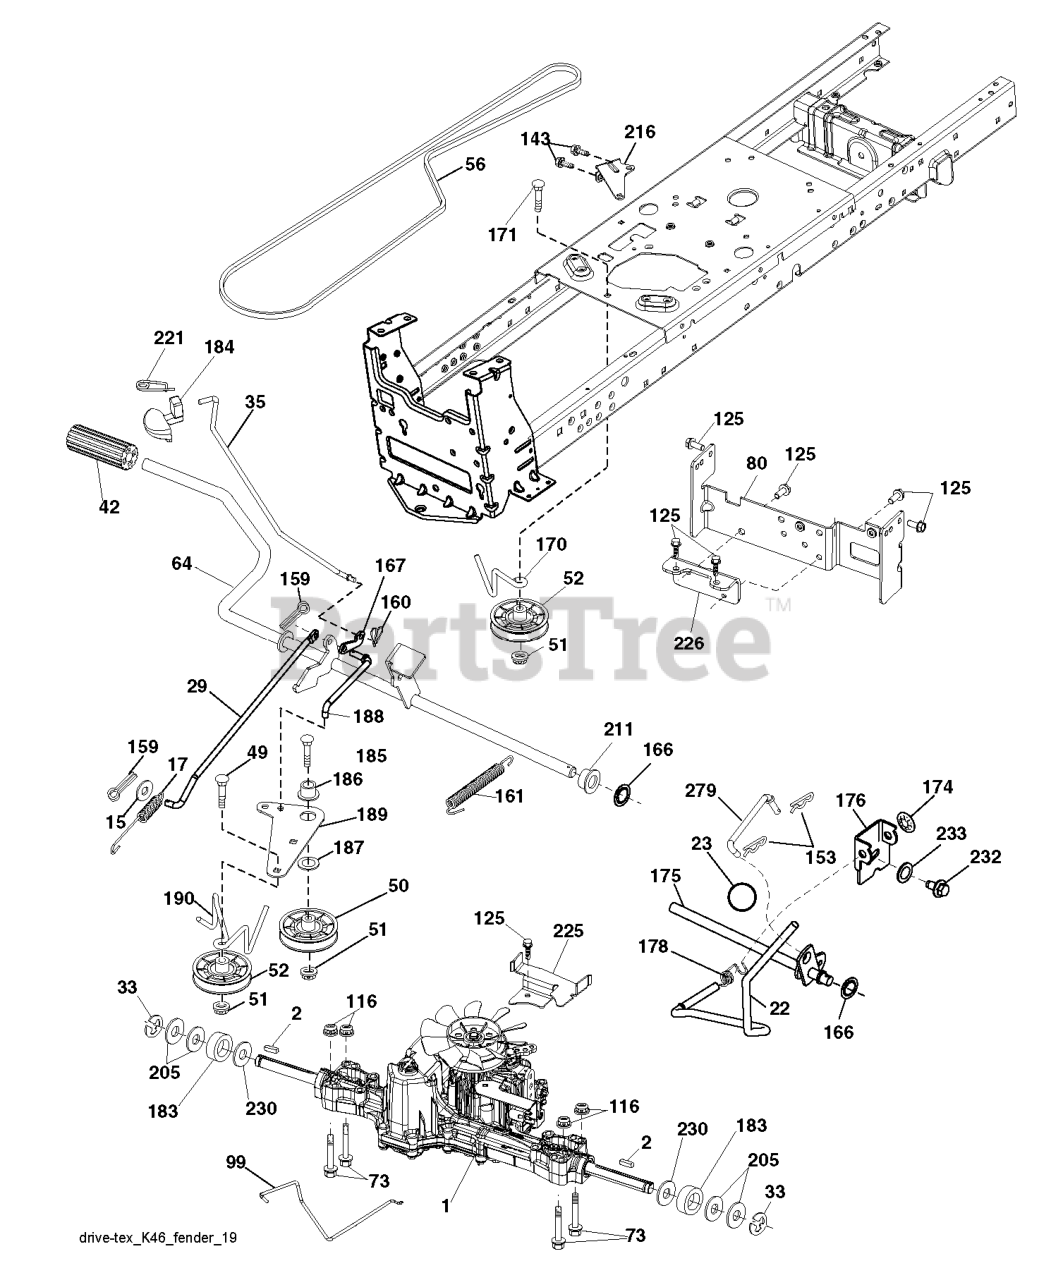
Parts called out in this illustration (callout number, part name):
2	SQUARE KEY
15	WASHER
17	SPRING.BRAKE.K46.GREEN
22	ROD.SHIFT.FENDER.TLT.2006
23	KNOB.DUCKHEAD.1/2
29	ROD.BRAKE.K46
35	ROD.CNTRL.PARK.PREDATOR.LT.TEX
42	PEDAL COVER T
50	IDLER.FLAT.910.OFFSET
51	NUT LOCK FLG 3/8-16 UNC
52	IDLER.V-GROOVE.910.OFFSET
56	V-BELT.MOWER.92.40.42/K46
64	SHAFT.ASM.PEDAL.BRAKE.
73	BOLT HEX 5/16-18 GR 5
80	STRAP TORQUE
99	ROD.SPRING.BYPASS.K46.LT.Z
116	NUT LOCK HEX FLANGE 5/16-18
125	SCREW
143	Screw 5/16-18 x 1/2 Hex, Self Tapping 5/16-18 x 1/2
153	RETAINER M
159	COTTER PIN
160	RETAINER CLIP
161	SPRING, RETURN LT
166	NUT.PUSH.625
167	LATCH.BRAKE.SPRING
170	KEEPER.V-IDLER.CENTER.
171	BOLT
174	NUT.PUSH.500.2006
175	SHAFT ASM SHIFT
176	ARM.CLEVIS.ROD.SHIFT
178	SPRING.SHIFT.GT2006
183	SPACER AXLE
184	HANDLE PARKING BRAKE
186	SPACER.RETAINER
187	WASHER 12/32X2X10GA
188	RP.LINK.CLUTCH.GROUND.DRIVE
189	BELLCRANK.GROUND.DRIVE.TEX.
190	KEEPER.BELLCRANK.DRIVE
211	BUSHING.SHAFT.BRAKE.HAND
216	BRACKET.PULLEY.IDLER.W/TEX
221	RETAINER.SPRING.CLIP.H
225	KEEPER.BELT.TRANSAXLE.K46
226	BRACKET.MOUNT.TORQUE.K46.TLT
230	WASHER.HARDENED
232	BOLT FIN HEX 7/16-14 X 1
233	WASHER SERRATED
279	LINK.SHIFT.T/A.K46.FEND.TX
